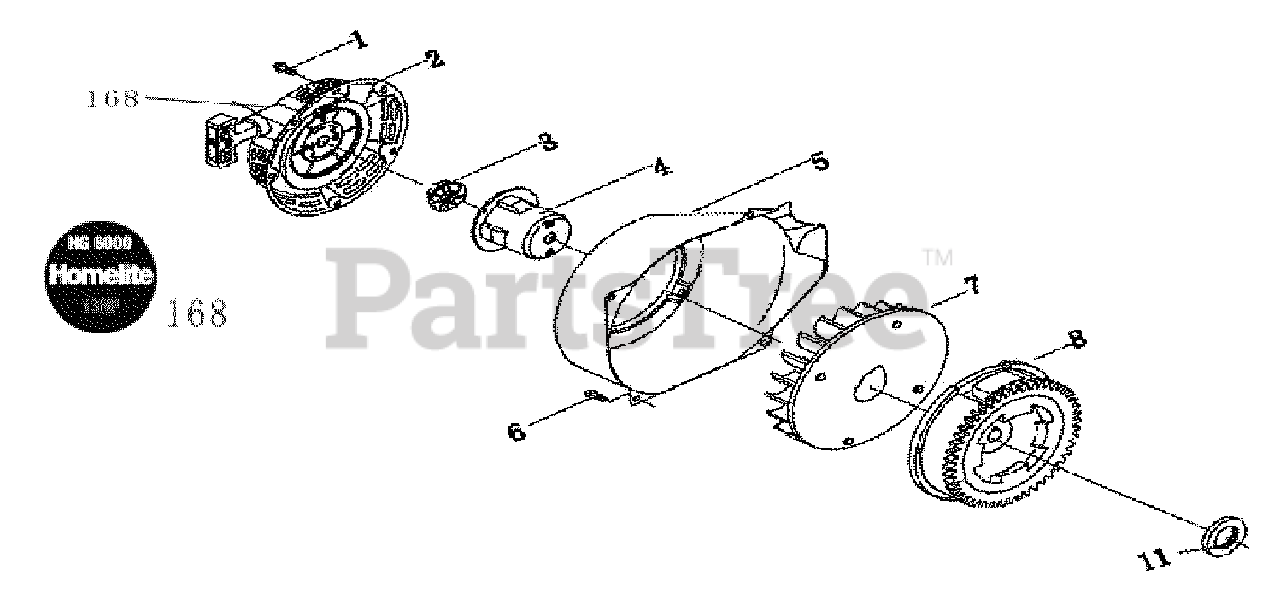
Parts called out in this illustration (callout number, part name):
1	M6 x 12 flanged bolt
2	Recoil starter
3	M14 x 1.5 flanged nut
4	Starter pulley
5	Wind leader
6	M6 x 12 flanged bolt
8	Flywheel
168	Engine recoil starter label
